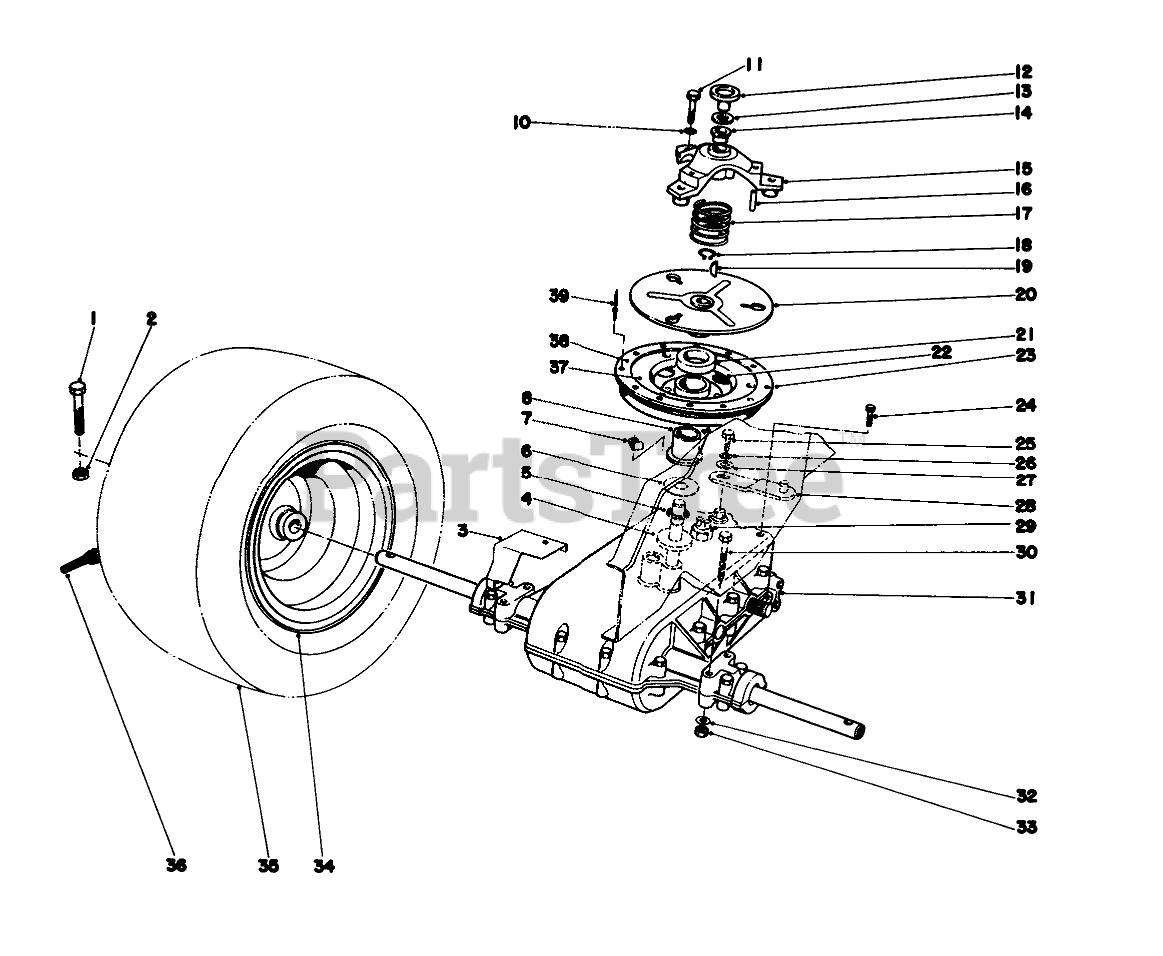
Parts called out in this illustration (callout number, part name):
1	SCREW-HH
2	NUT-LOCK, CONE
3	GRASS SHIELD B
4	THRUST WASHER
5	NEEDLE BRG
6	THRUST WASHER
7	CLIP-FUEL LINE
8	Bushing
10	WASHER-LOCK
11	SCREW-HH
12	CLUTCH CAP
13	THRUST RACE
14	BUSHING-FLANGE
15	Cover Assembly (Incl. Ref. #14 & 16)
16	NEEDLE BRG
17	COMPRESSION SPRING
18	RING-SNAP, EXTERNAL
19	KEY-WOODRUFF
20	Clutch Plate
21	WASHER FELT
23	Sheave Assembly (Incl. Ref. #8, 37-39)
24	SCREW-HWHTF
25	SCREW-HH
26	WASHER-LOCK
27	WASHER-FLAT
28	SHIFT LEVER WA B
29	NEUTRAL SWITCH
30	SCREW-HH
31	Transaxle
32	WASHER-PLAIN
33	NUT-LOCK, CONE
35	Tire
36	STEM-VALVE
37	Retainer Ring
38	CLUTCH PAD
39	RIVET-POP
